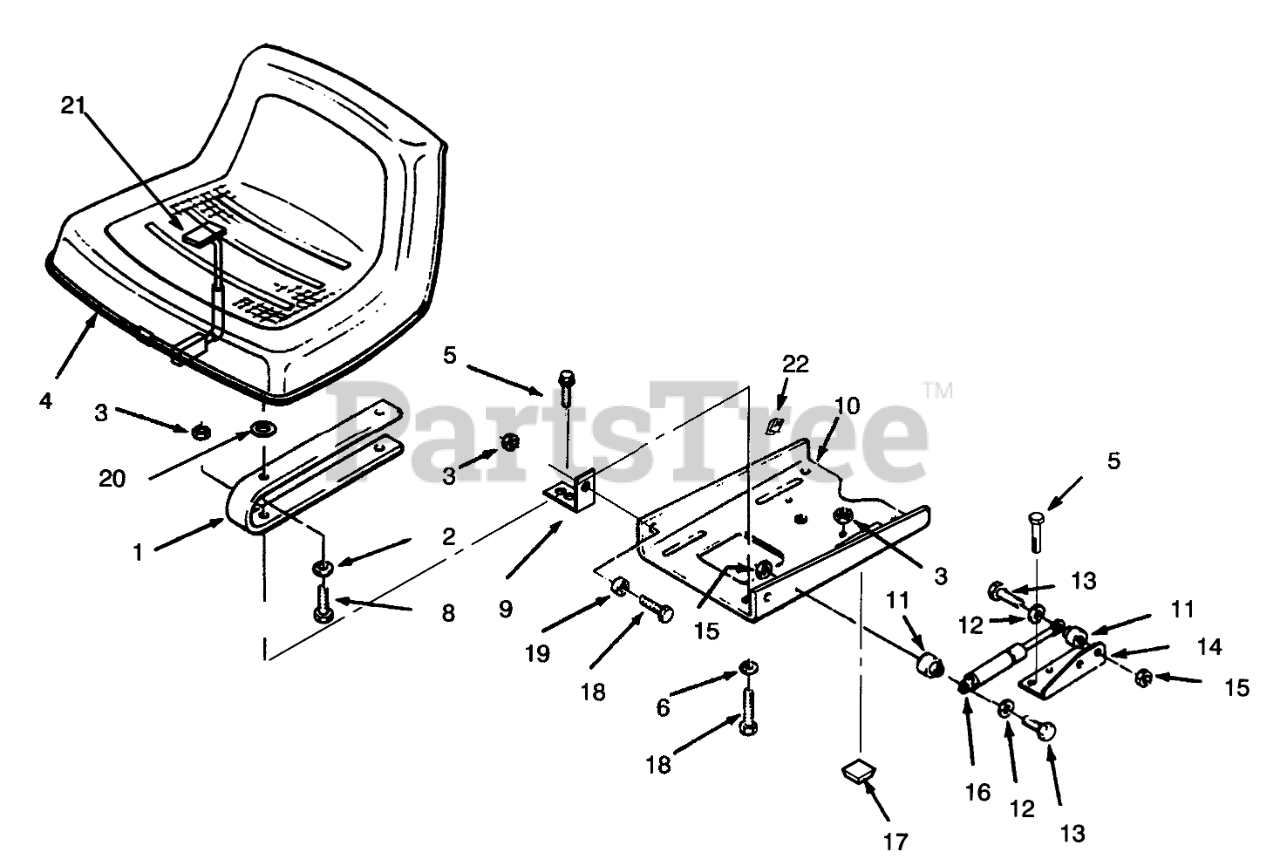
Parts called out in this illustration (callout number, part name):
1	Seat Spring
2	WASHER-LOCK
3	NUT-LOCK, NI
5	Screw
6	WASHER-PLAIN
8	SCREW-HH
9	BRACKET-PIVOT
10	Plate-SeatPivot
11	SPACER
12	WASHER-FLAT
13	SCREW-HH
14	BRACKET-CYLINDER R
15	NUT-LOCK, NI
16	GAS SPRING
17	BUMPER SJ5514 BLACK
18	SCREW-HH
19	BUSHING
20	SPACER-NYLON
21	SWITCH-SEAT
22	SPEED CLIP
